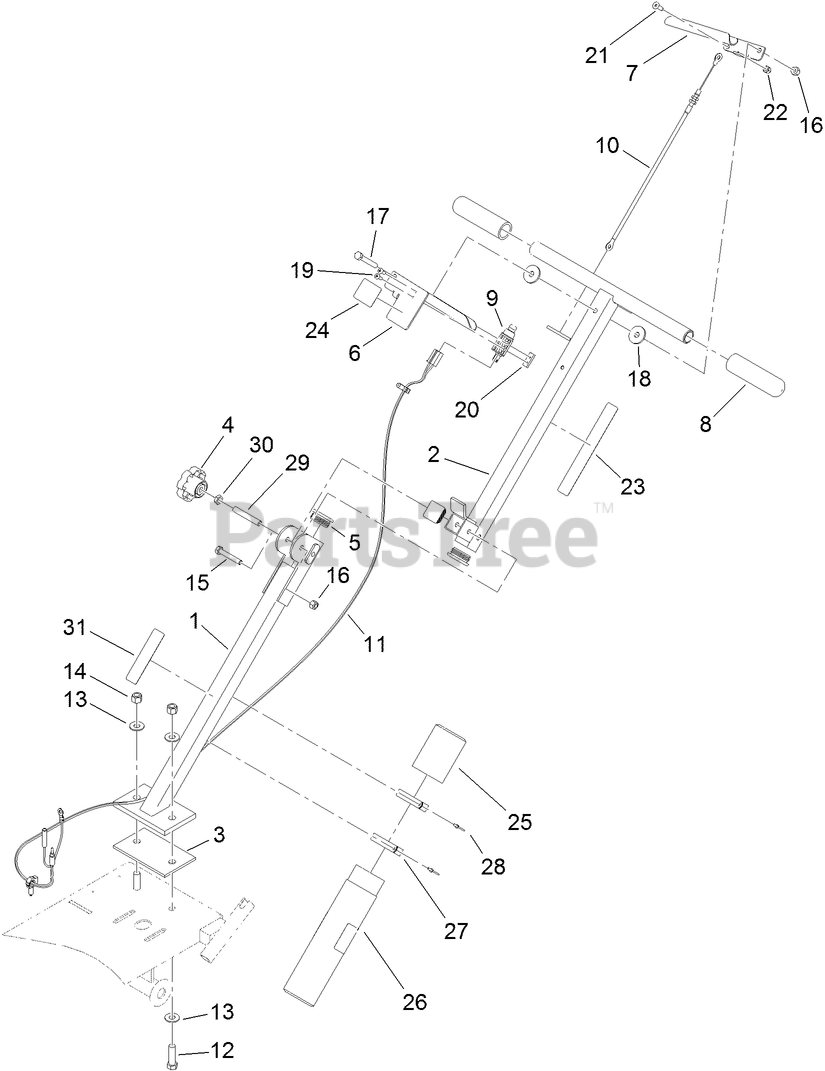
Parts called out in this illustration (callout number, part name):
1	HANDLE-LOWER
2	UPPER HANDLE ASM
3	GASKET-HANDLE
5	PLUG-TUBE
6	PLUNGER HANDLE ASM
7	HANDLE-THROTTLE
8	GRIP-HANDLE
9	SWITCH-PLUNGER, NC (W/COVER)
10	CABLE-THROTTLE
11	HARNESS-WIRE
12	SCREW-HH
13	WASHER-FLAT
14	NUT-LOCK, NI
15	SCREW-HH
16	NUT-LOCK, NI
17	SCREW-HH
18	WASHER
20	PLATE-TAPPED
21	SCREW-TORX
22	NUT-LOCK, NI
23	DECAL-CAUTION
24	DECAL-ENGAGE
25	CAP-HOUSING
26	TUBE-MANUAL
27	CLAMP-R
28	RIVET-POP
29	SCREW-HSH
30	NUT-JAM
31	DECAL-ARRESTER, SPARK
